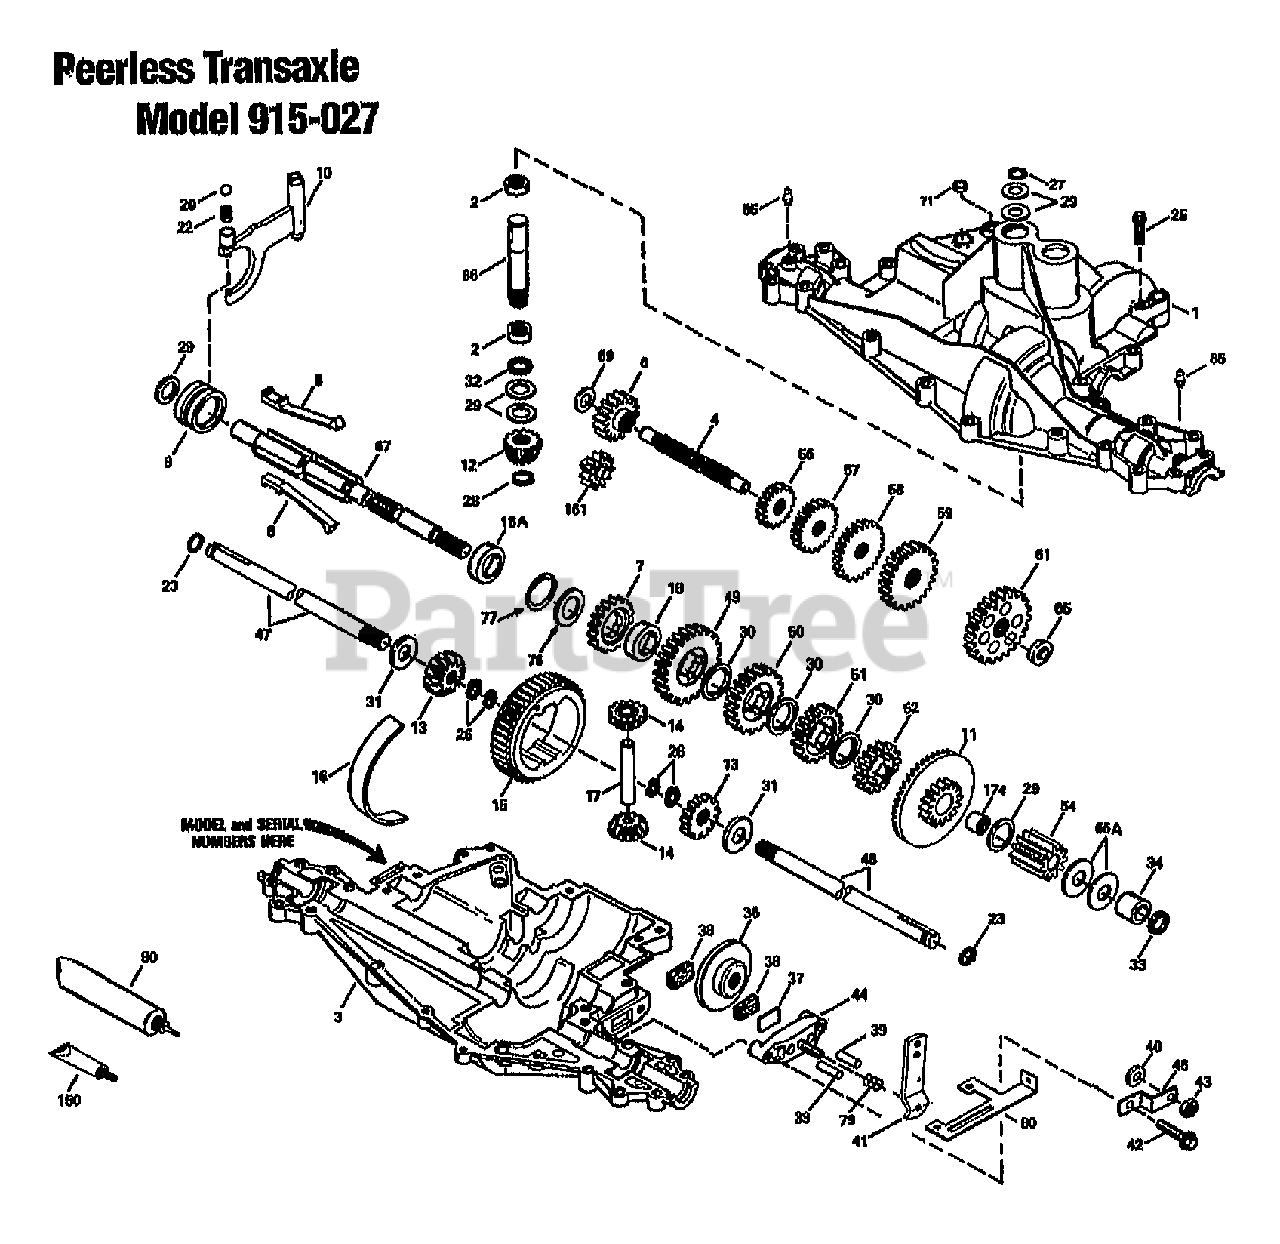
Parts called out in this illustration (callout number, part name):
1	TRANSAXLE COVER
2	NEEDLE BEARING
3	TRANSAXLE CASE
4	COUNTERSHAFT
6	SPUR GEAR (16 TEETH)
7	SPUR GEAR (22 TEETH)
8	SHIFT KEY
10	SHIFT ROD & FORK
11	BEVEL GEAR & BEARING (INCL. 174)
12	BEVEL PINION (14 TEETH)
13	BEVEL GEAR (16 TEETH)
14	DIFFERENTIAL PINION
15	RING GEAR
16	BEARING STRIP
17	DRIVE PIN
18	NEUTRAL SPACER
18A	NEUTRAL SPACER
20	BALL, 5/16" DIA.
22	SPRING
23	SEAL RING
25	SCREW, 1/4-20 X 1-1/4"
26	RETAINING RING
27	RETAINING RING
28	RETAINING RING
29	WASHER
30	WASHER
32	"O" RING
33	"O" RING
36	BRAKE DISK
37	BRAKE PAD PLATE
38	BRAKE PAD (PKG OF 2)
39	DOWEL PIN
41	BRAKE LEVER
42	SCREW, 1/4-20 X 1-1/4"
43	LOCKNUT, 5/16-24
44	BRAKE PAD HOLDER
46	BRAKE LEVER BRACKET
47	AXLE (16-1/4" LONG)
48	AXLE (11" LONG)
49	SPUR GEAR (30 TEETH)
50	SPUR GEAR (25 TEETH)
51	SPUR GEAR (22 TEETH)
52	SPUR GEAR (19 TEETH)
54	SPUR GEAR (11 TEETH)
56	SPUR GEAR (20 TEETH)
57	SPUR GEAR (25 TEETH)
58	SPUR GEAR (28 TEETH)
59	SPUR GEAR (30 TEETH)
61	SPUR GEAR (34 TEETH)
66	INPUT SHAFT
67	SHIFTER & BRAKE SHAFT
71	SQUARE CUT RING
77	INVERTED RETAINING RING (PKG OF 2)
80	BRAKE BRACKET
85	LUBRICATION FITTING
90	GREASE (32OZ. BTL. BENTONITE GREASE)
150	GASKET ELIMINATOR (LOCTITE #515)
161	REVERSE IDLER
174	NEEDLE BEARING
